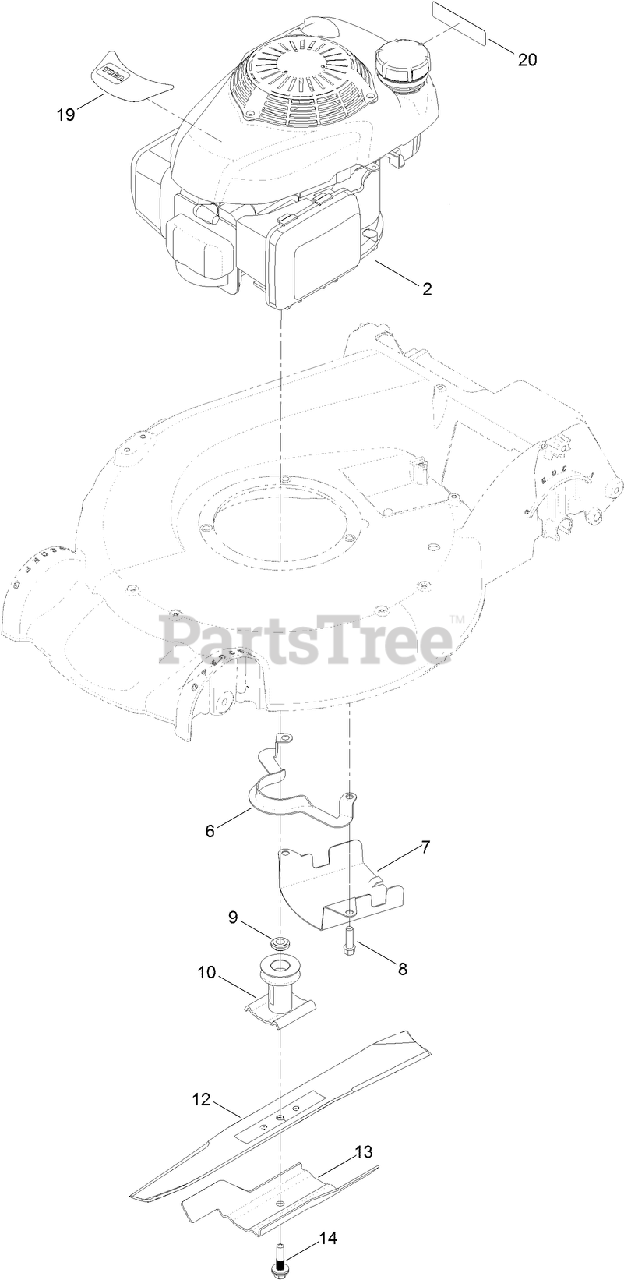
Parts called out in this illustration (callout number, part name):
6	GUIDE-BELT
7	SHIELD-GRASS
8	SCREW-TAPTITE
9	SPACER-DRIVER
10	DRIVER-BLADE
13	ACCELERATOR-BLADE
14	BOLT-BLADE
19	DECAL-SHROUD, HONDA
20	DECAL-ARRESTER, SPARK
